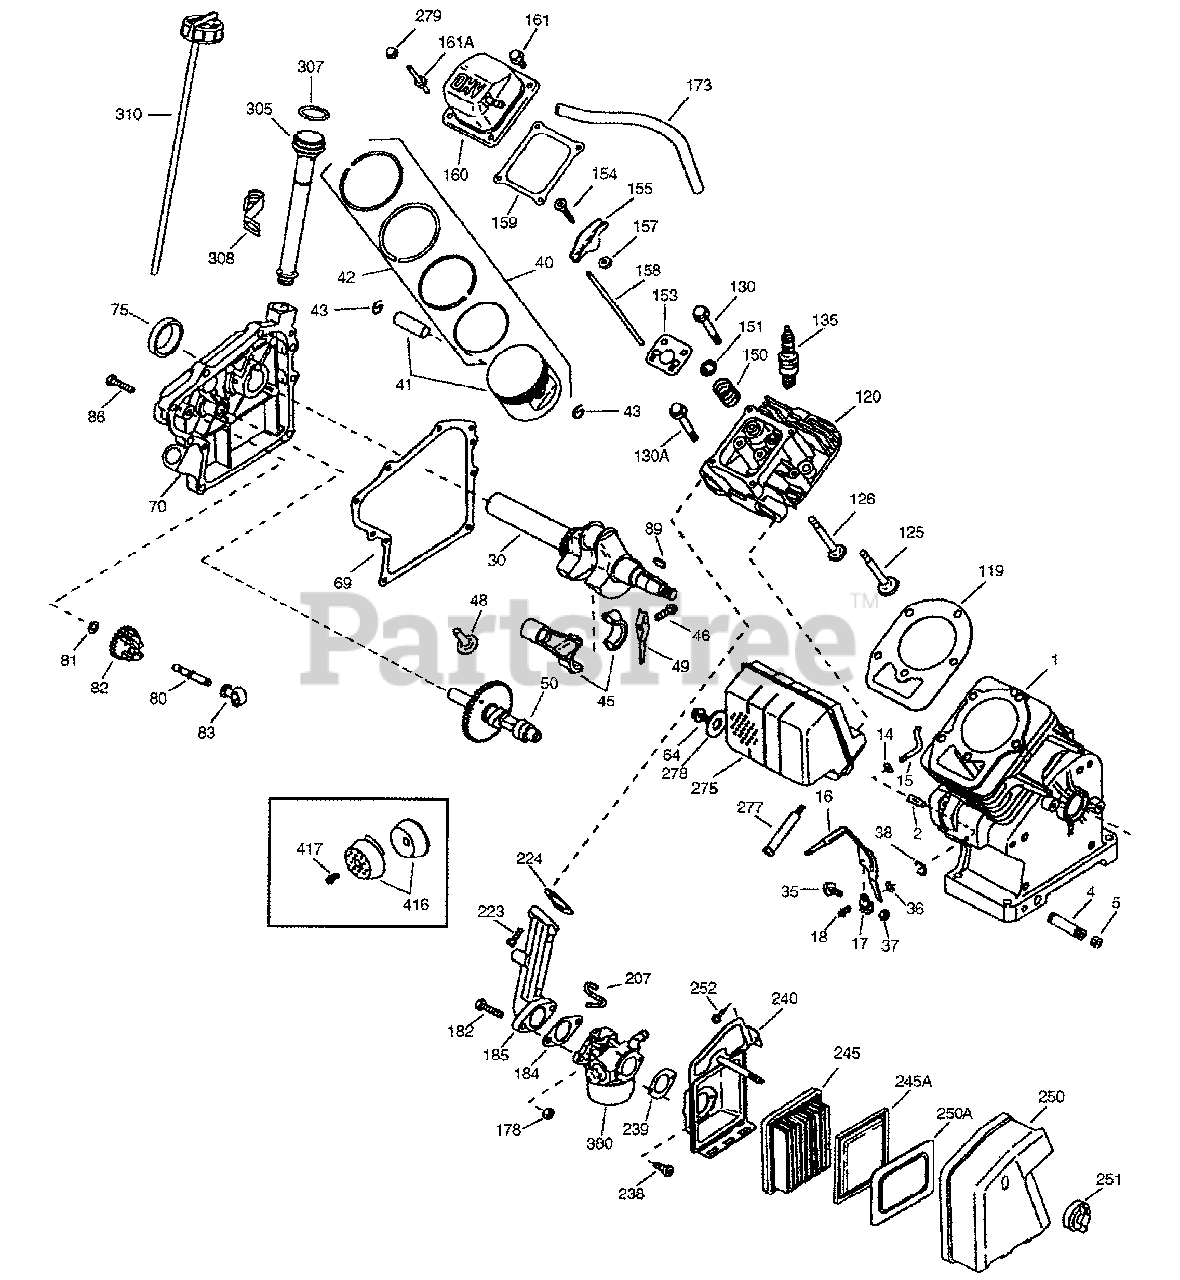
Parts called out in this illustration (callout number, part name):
1	Cylinder
2	Dowel Pin
4	Oil Drain Extension
5	Extension Cap
15	Governor Rod
16	Governor Lever
17	Governor Lever Clamp
18	Screw, Torx T-15, 8-32 x 3/8"
30	Crankshaft
35	Screw, 10-32 x 3/4"
36	Lock Washer
37	Lock Nut, 10-32
38	Retaining Ring
40	Piston, Pin & Ring Set (Standard)
41	Piston & Pin Ass'y (Standard)
42	Ring Set (Standard)
43	Piston Pin Retaining Ring
45	Connecting Rod Ass'y
46	Connecting Rod Bolt
48	Valve Lifter
49	Oil Dipper
64	Screw, 1/4-20 x 1-1/8"
69	Cylinder Cover Gasket
70	Cylinder Cover
80	Governor Shaft
82	Governor Gear Ass'y
83	Governor Spool
86	Screw, 1/4-20 x 1-1/4"
89	Flywheel Key
119	Cylinder Head Gasket
120	Cylinder Head
125	Exhaust Valve (Standard)
126	Intake Valve (Standard)
130	Screw, 5/16-18 x 1-1/2"
130A	Screw, 5/16-18 x 2-41/64"
135	Resistor Spark Plug (N4C)
150	Valve Spring
151	Valve Spring Cap
153	Push Rod Guide
154	Rocker Arm Stud
155	Rocker Arm
157	Nut, 1/4-28
159	Rocker Arm Cover Gasket
160	Rocker Arm Cover
161	Screw, 1/4-20 x 31/64"
173	Breather Tube
178	Nut, 1/4-20
182	Screw, 1/4-20 x 1"
184	Carb. to Intake Pipe Gasket
185	Intake Pipe
207	Throttle Link
223	Screw, 1/4-20 x 1"
224	Intake Pipe Gasket
238	Screw, 10-32 x 1/2"
239	Air Cleaner Gasket
240	Air Cleaner Body
245	Air Cleaner Filter
245A	Air Cleaner Filter (Poly)
250	Air Cleaner Cover
250A	UKNOWN
252	Screw, 10-32 x 31/64"
277	Screw, 1/4-20 x 2-9/32"
279	Nut & Lock Washer
305	Oil Fill Tube
308	Fill Tube Clip
310	Dipstick
380	Carburetor Ass'y
416	Spark Arrestor Kit
417	Screw, 8-32 x 3/8"
